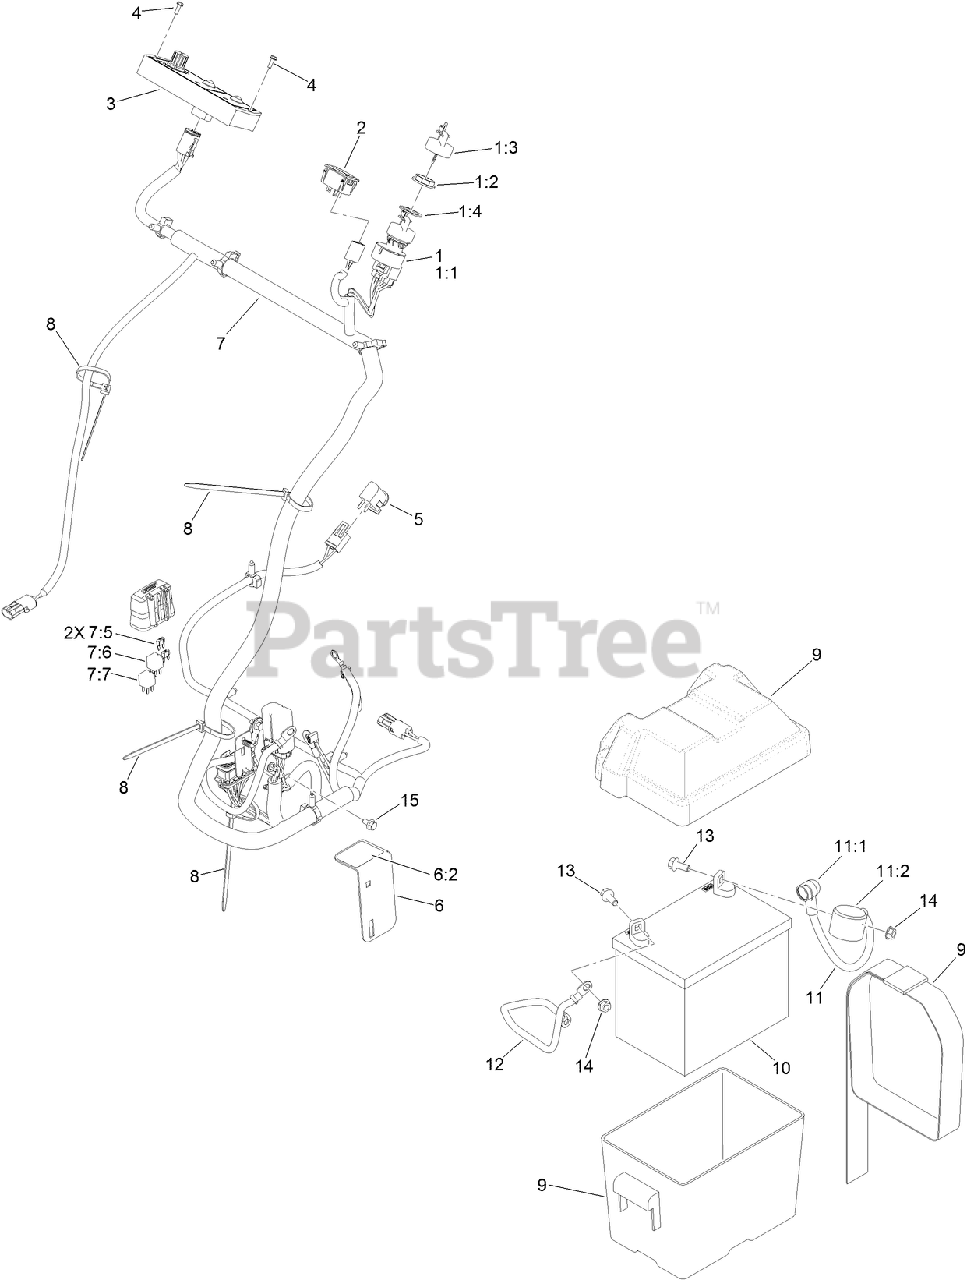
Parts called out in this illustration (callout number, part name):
1	IGNITION SWITCH ASM
1:1	Deck ASM
1:2	NUT-MOUNTING
1:3	IGNITION KEY SET
1:4	WASHER-BACKUP
2	METER-HOUR
3	CONTROLLER-DC
4	SCREW-HWHTF
5	SWITCH-BAIL
6	FUSE BRACKET ASM
6:2	DECAL-PDM
7	HARNESS-WIRING
7:5	FUSE-MINI BLADE, 20 AMP
7:6	RELAY-MICRO
7:7	RELAY-COIL, NC, MP280
8	TIE-PLASTIC
9	BATTERY BOX
10	BATTERY
11	POSITIVE BATTERY CABLE ASM
11:1	INSULATOR-SOLENOID
11:2	INSULATOR-BATTERY
12	CABLE-BATTERY, NEGATIVE
13	SCREW-HHF
14	NUT-HF
15	SCREW-HHF
